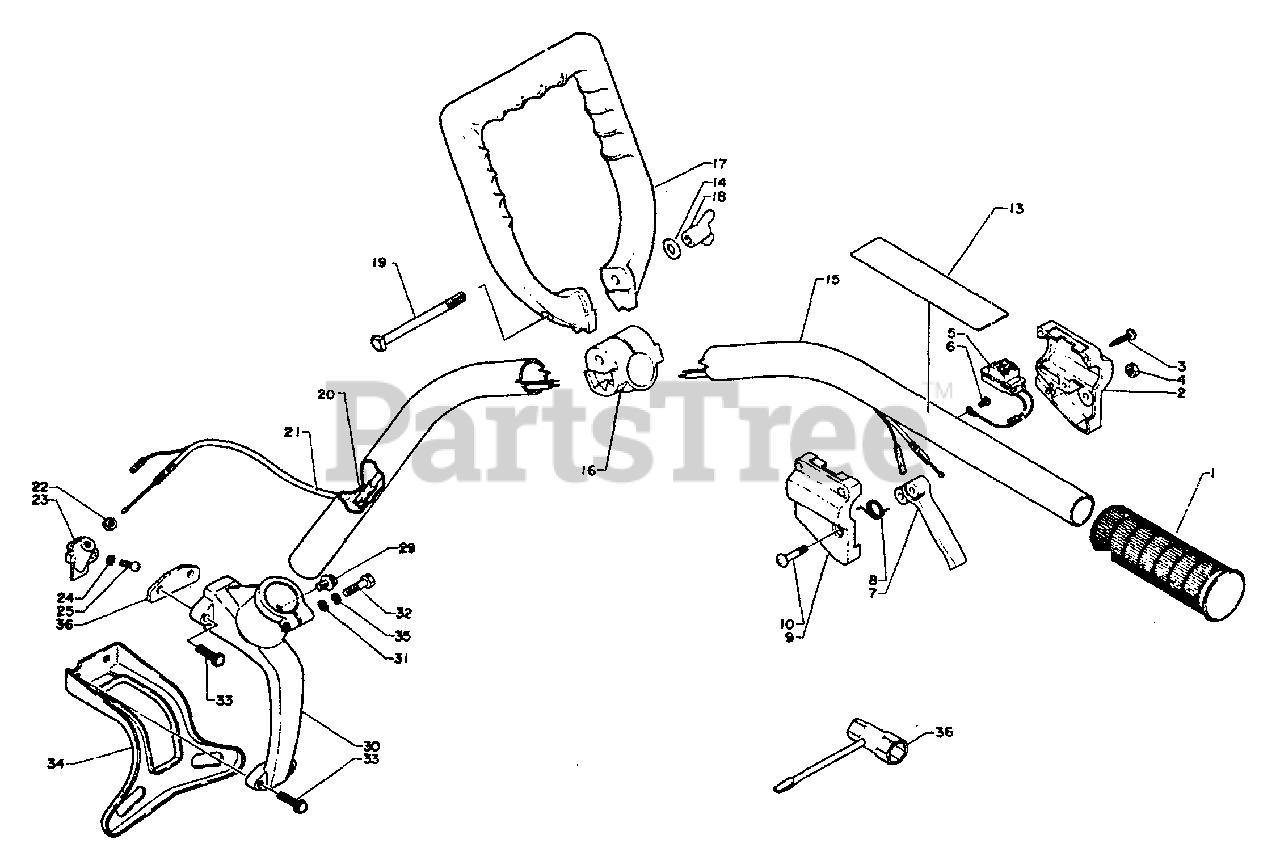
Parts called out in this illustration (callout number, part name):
1	GRIP
2	BRACKET, TRIGGER
3	SCREW - 4X25
4	LOCKNUT - 5
5	IGNITION SWITCH ASSY
6	SCREW - 4X8
7	TRIGGER, THROTTLE
8	SPRING, TRIGGER
9	BRACKET - LEFT
10	SCREW - 5X30
13	LABEL - CAUTION
14	WASHER - 6
15	PIPE, MAIN
16	BRACKET, HANDLE
17	HANDLE
18	NUT - 6 -- BUTTERFLY
19	BOLT
20	COVER, THROTTLE CABLE
21	CABLE, THROTTLE
23	BRACKET, THROTTLE CABLE
24	WASHER - 4
25	SCREW - 4X12
26	WASHER - 6
29	SCREW - 5X10
30	BRACKET
31	WASHER - 5
32	BOLT - 5X25
33	SCREW - 5X20
34	STAND
35	LOCKWASHER - 5
36	T-WRENCH
